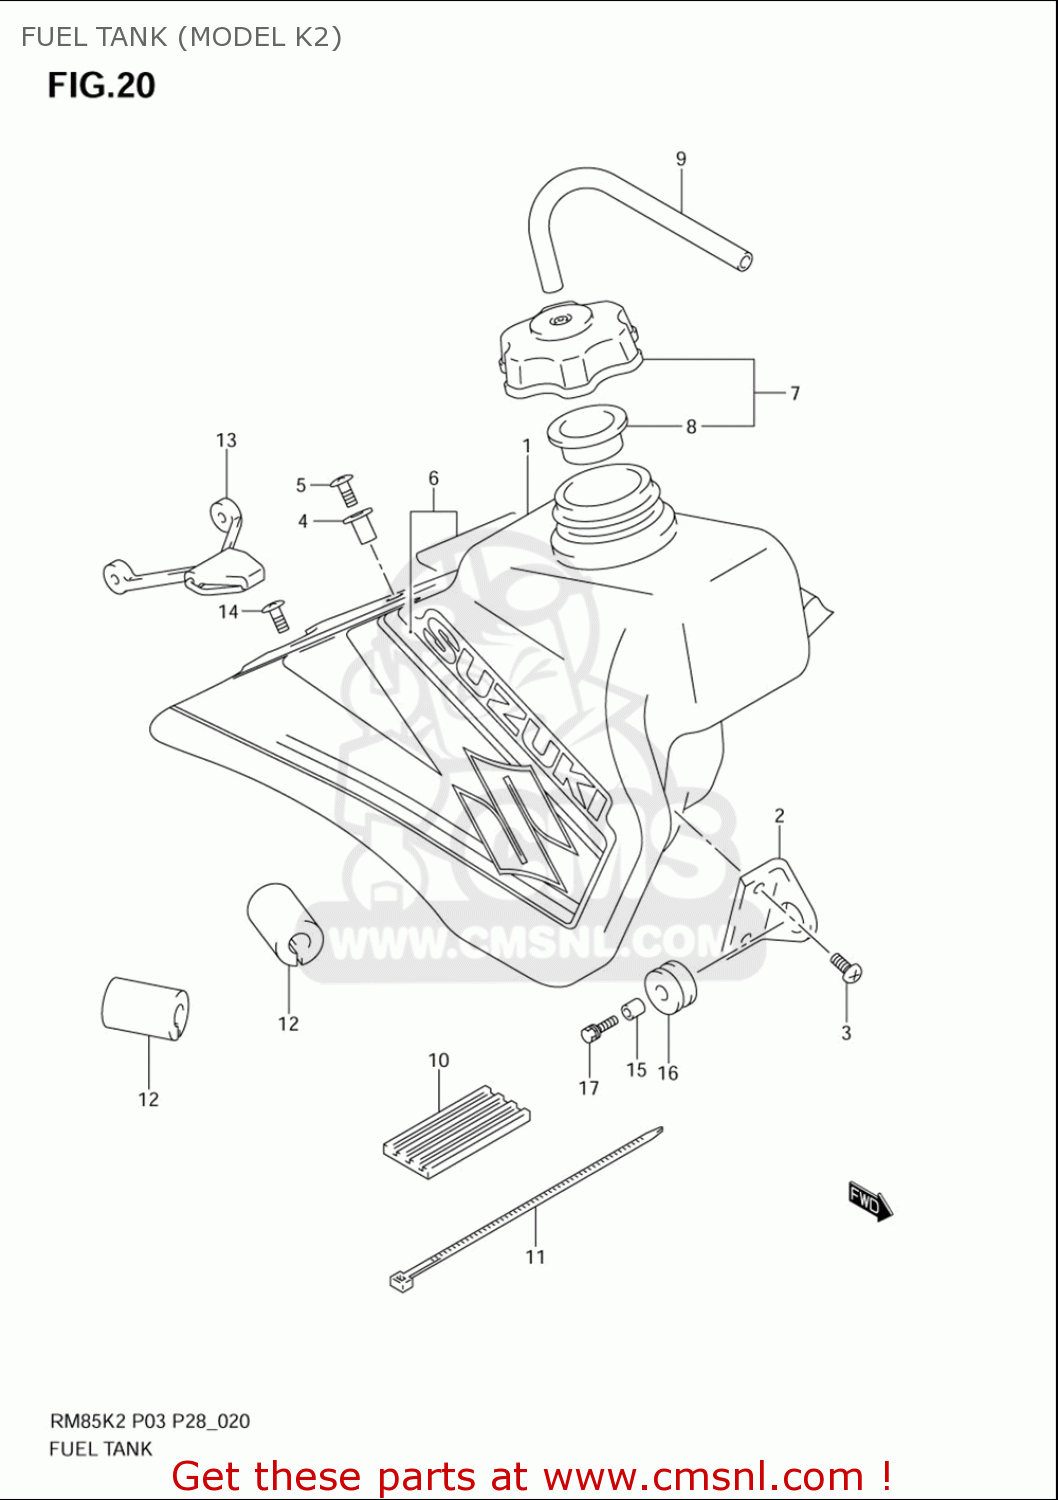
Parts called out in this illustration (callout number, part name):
1	TANK,FUEL
2	BRACKET,FUEL TANK FR
3	SCREW
4	HOOK,SEAT FR
5	SCREW
6	TAPE SET,FUEL TANK
7	CAP SET,FUEL TANK
8	GASKET,CAP (NAS)
9	HOSE(5X8.2X600)
10	CUSHION,FUEL TANK UPR FR
11	CLAMP(L:250)
12	CUSHION,FUEL TANK UPR RR
13	BAND,FUEL TANK RR
14	SCREW
15	SPACER(6.5X9X13.5)
16	CUSHION,MUFFLER
17	BOLT(6X25)
